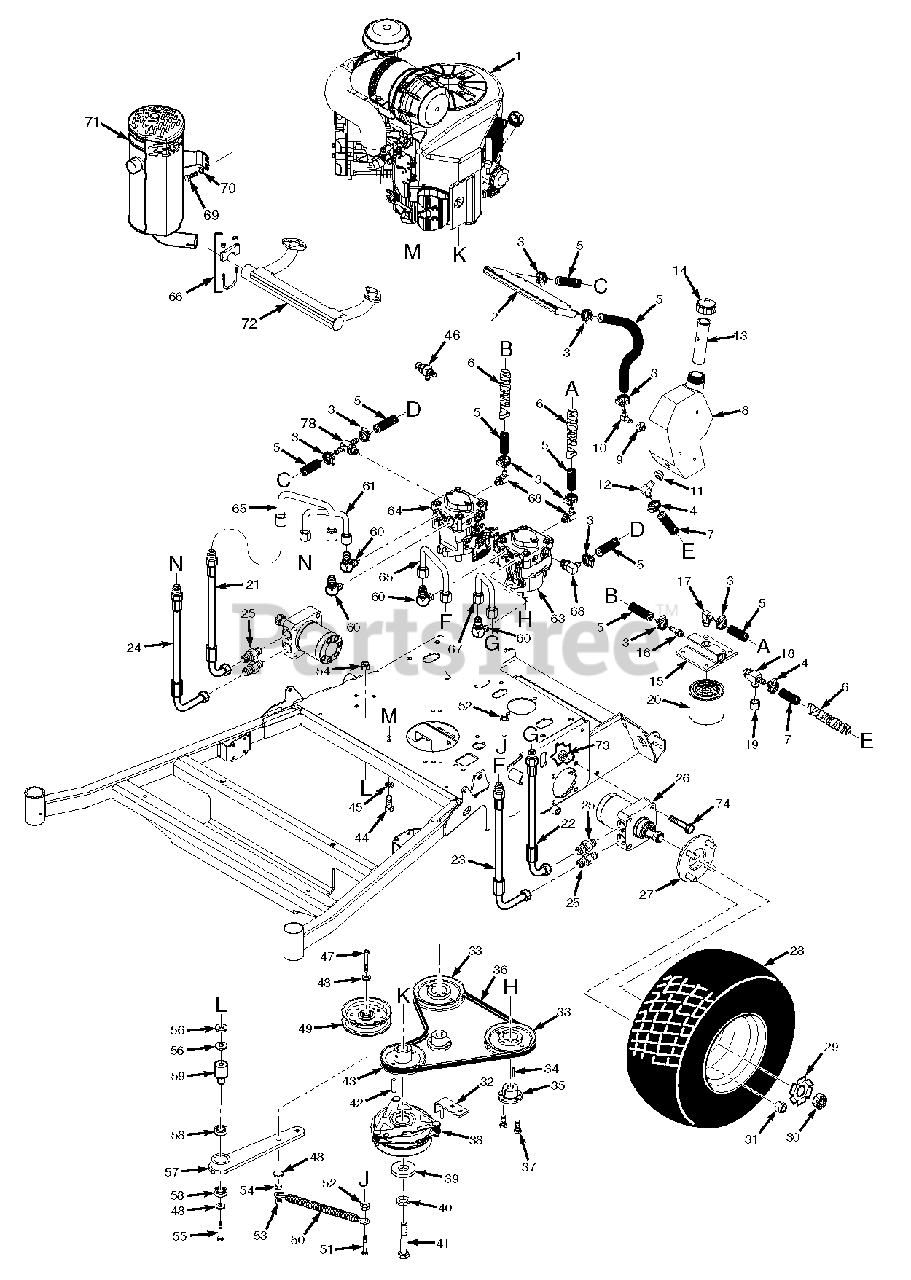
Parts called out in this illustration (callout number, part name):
1	Engine, 15hp Kawasaki FS541V
1	Engine, 19hp Kawasaki FX600V
1	Engine, 22hp Kawasaki FX691V
2	Cooler, Transmission (48V)
3	Clamp, .69 Max Dia.
4	Clamp, .87 Max Dia.
5	Hose, 3/8 Pushlock
6	Heatshield, Flexible
7	Hose, 1/2 Pushlock
8	Hydraulic Tank Assy.
9	Bushing, .56 Dia, Viton
10	Fitting, 90 Degree - .38 Hose
11	Bushing, .78 Dia. Viton
12	Fitting, 90 Degree - .50 Hose
13	Insert, Filler Neck
14	Cap, Hydraulic Tank
15	Filter Head
16	Fitting
17	Elbow, 90 Degree
18	Tee Fitting, 3/4 O-Ring
19	Cap, 3/4" JIC
20	Oil Filter
21	Hose Assembly
22	Hose Assembly
23	Hose Assembly
24	Hose Assembly
25	Fitting, Union 1/2 x 5/8
26	Wheel Motor
27	Wheel Hub
28	Wheel Assembly (36)
28	Wheel Assembly
28	Rim w/Valve Stem (36)
28	Rim w/Valve Stem
28	Tire, 18 x 8.5-8 (36)
28	Tire, 20 x 10.5-8
29	Lockwasher, Wheel Motor
30	Hex Castle Nut, 3/4-28
31	Wheel Nut
32	Anti-Rotation Bracket (36A)
32	Anti-Rotation Bracket (48V)
33	Pulley, 5.45 OD - Tapered Bore
34	Key, 5 x 5 x 25mm
35	Tapered Hub, 15mm Bore
36	Belt, Pump Drive (36)
36	Belt, Pump Drive (48)
37	Bolt, Hex Head 1/4-20 x 1" Gr. 8
38	Clutch w/Tag (36A, 48V)
39	Flatwasher, 7/16-.469 x 1.75 x .25
40	Lockwasher, 7/16" Spring
41	Bolt, Hex Head 7/16-20 x 2-1/4" Patch
42	Key, 1/4 x 1/4 x 3-1/2"
43	Pulley, 4.75 OD - 1.125" Bore
44	Bolt, Hex Head 3/8-16 x 1-1/4"
45	Lockwasher, 3/8" Spring
46	Oil Drain
47	Bolt, Hex Head 3/8-16 x 2-3/4"
48	Flatwasher, 3/8-.391 x .938 x .105 HD
49	Pulley, 4-1/2" Idler
50	Spring, Transmission
51	Bolt, Hex Head 3/8-16 x 3"
52	Nut, Serrated Flange 3/8-16
53	Nut, Center Lock 3/8-16
54	Nut, Elastic Stop 3/8-16
55	Bolt, Hex Head 3/8-16 x 3-1/4"
56	Flatwasher, 3/8-.375 x 1-1/2 x .059
57	Idler Arm Assy
58	Bearing
59	Idler Pivot, Long
60	Elbow, 90 Degree - 1/2 x 1/2
61	1/2" U-Tube Assembly, 4" Wide
62	Tubing, Oil Drain
63	Pump, LH - 10cc (36)
63	Pump, LH - 10cc w/Shock Valves (48)
64	Pump, RH - 10cc (36)
64	Pump, RH - 10cc w/Shock Valves (48)
65	1/2: U-Tube Assembly, 5" Wide
66	Clamp, Muffl er
67	1/2" U-Tube Assembly, 3" Wide
68	Elbow, 90 Degree
69	Bolt, Hex Head M8 - 1.25 x 20
70	Lockwasher, 5/16" Spring
71	Muffl er, Kawasaki (36)
71	Muffl er, Kawasaki (48V)
72	Exhaust Manifold, Kawasaki (48V)
73	Nut, Center Lock 1/2-13
74	Bolt, Hex Head 1/2-13 x 2-1/2"
